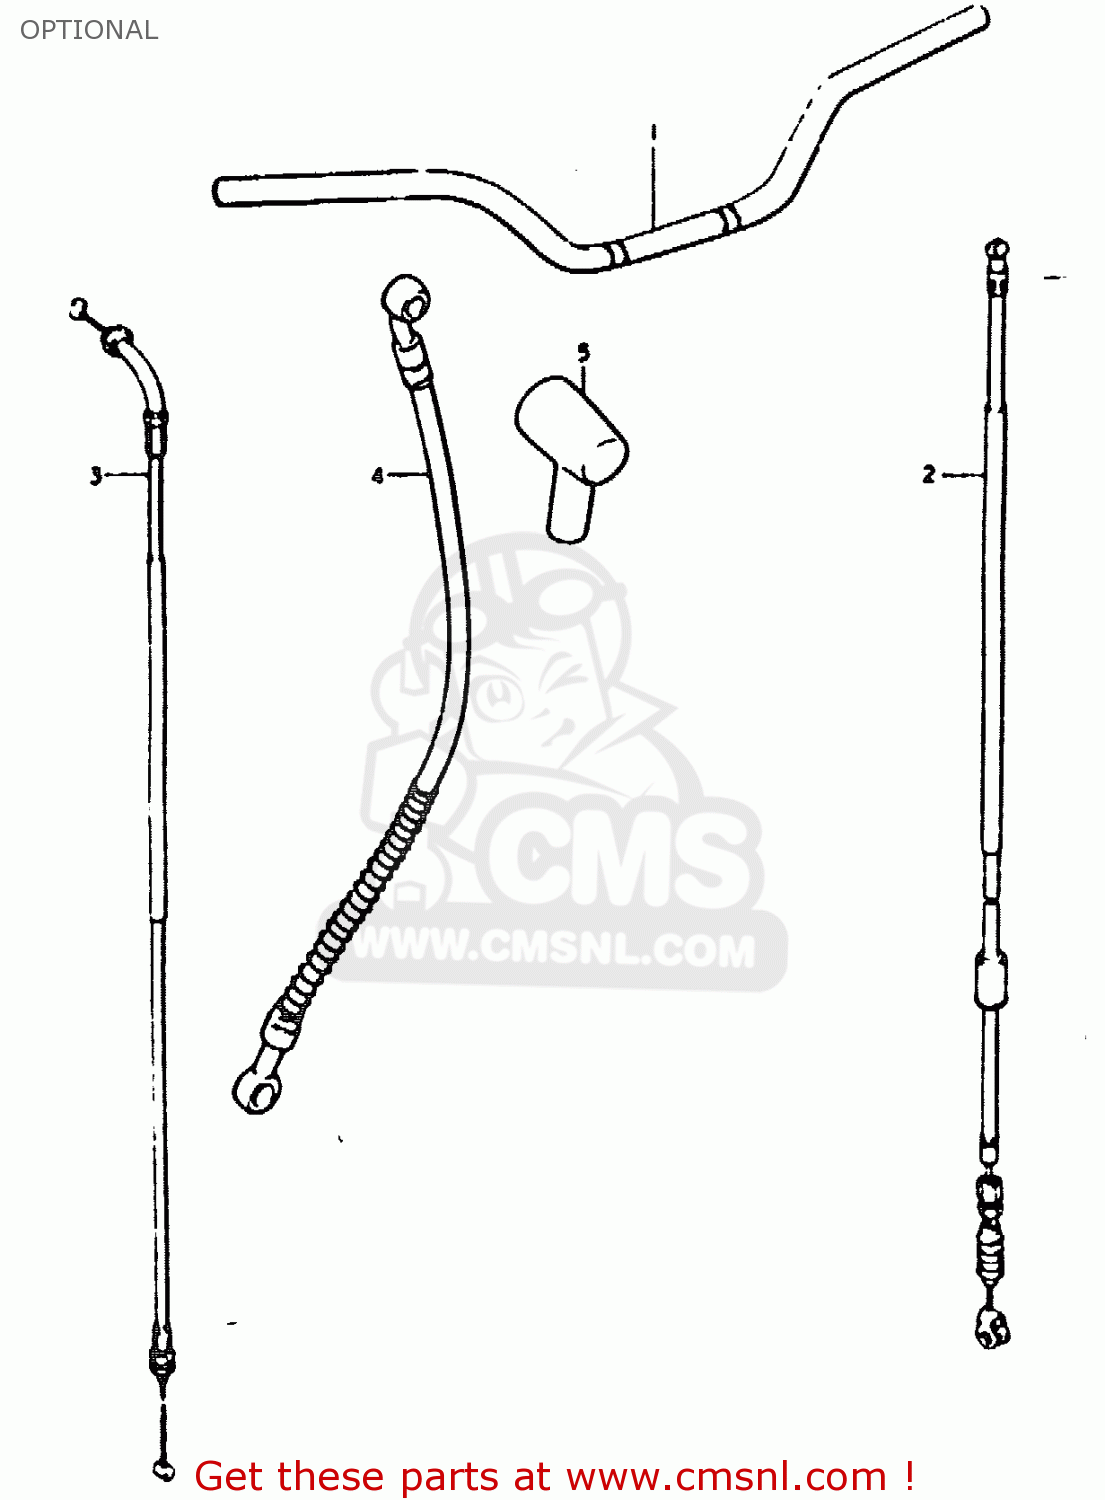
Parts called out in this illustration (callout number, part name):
1	HANDLEBAR
2	CABLE,CLUTCH
3	CABLE ASSY,THROTTLE
4	HOSE,FRONT BRAKE
5	BOOT
